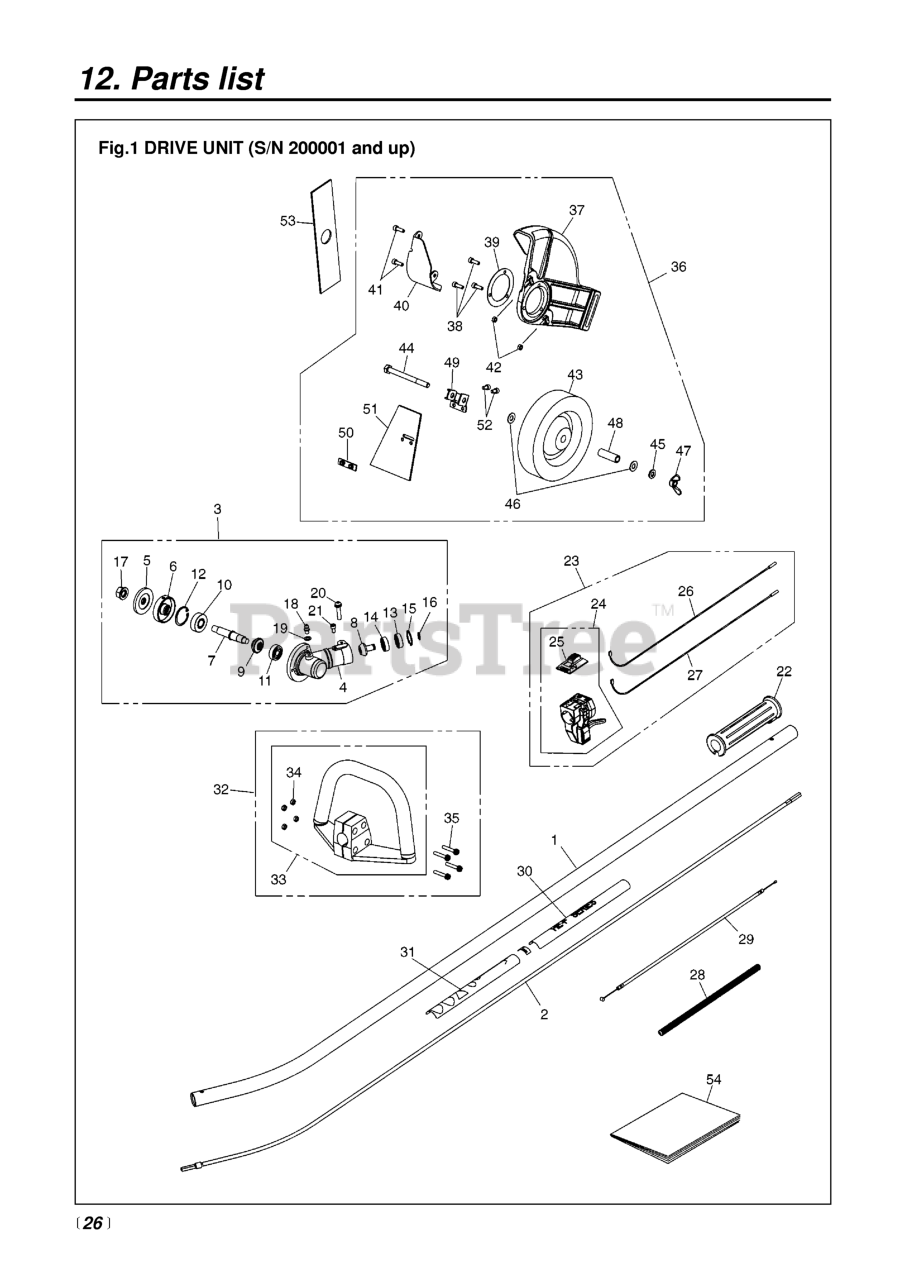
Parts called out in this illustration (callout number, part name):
1	PIPE COMP
2	SHAFT COMP
3	GEARCASE
4	GEARCASE
5	HOLDER B
6	HOLDER A
8	PINION
9	GEAR
10	BEARING
11	BEARING
12	RING, SNAP, M32 x 1.2
13	BEARING (RPLS T3300-13531)
14	BEARING (RPLS T3403-13530)
15	RING, SNAP, M24 x 1.2
17	NUT
18	FITTING, GREASE
19	WASHER, M6 X .8
20	BOLT
21	BOLT, M5 X 10
22	GRIP (RPLS 3577-32140 & 3220-
24	LEVER (USE 848-8R2-0313)
25	COVER (USE 848-8RA-0340)
26	CORD (A), BLACK
27	CORD (B), RED
28	TUBE (RPLS 4900-72141)
29	CABLE (RPLS 5580-83100)
30	NAME PLATE
31	PLATE, CAUTION
32	HANDLE ASSY.
33	HANDLE COMP.
35	SCREW, M5 x 30
36	GUARD ASSY.
37	GUARD
38	BOLT (M5x0.8-16)
39	PLATE
40	PROTECTOR
41	BOLT (M5x0.8-16)
42	NUT, M5 X 4
43	WHEEL
44	BOLT
45	WASHER, SPRING
46	WASHER, PLANE(USE 01640-20816)
48	SLEEVE
49	BRACKET
51	RUBBER (FLAP)
52	BOLT, M5 X 10
53	BLADE, EDGER (RPLS 147315)
54	MANUAL (HE225F / HEZ2500F)
